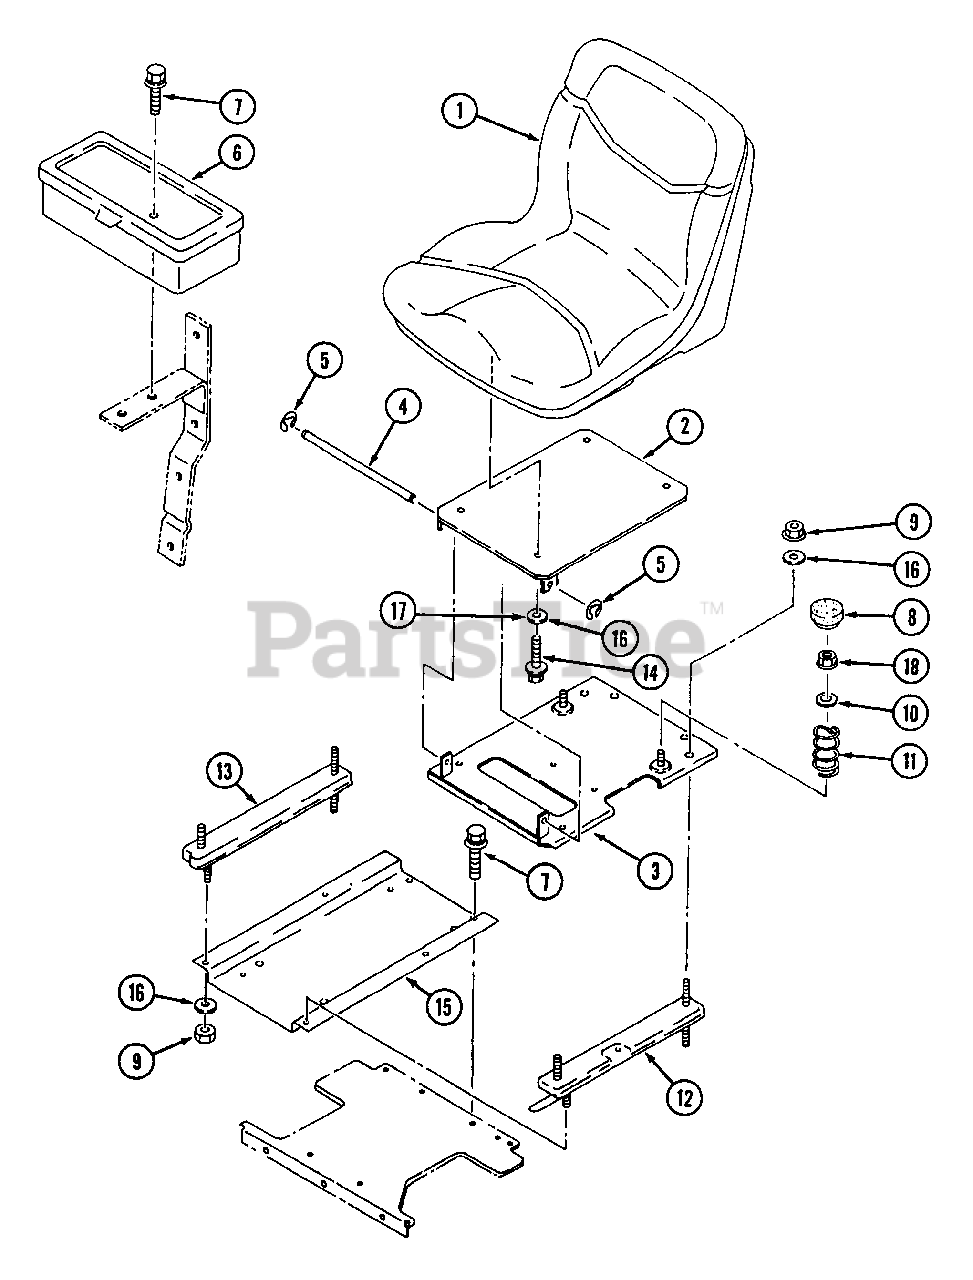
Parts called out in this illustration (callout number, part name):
1	Seat Ass'y.
3	Bracket, Seat
9	Nut, 8 mm
11	Spring
12	Adjuster, Slide
13	Rail, Slide
16	Washer, Lock, 5/16
17	Washer, Flat, 5/16
